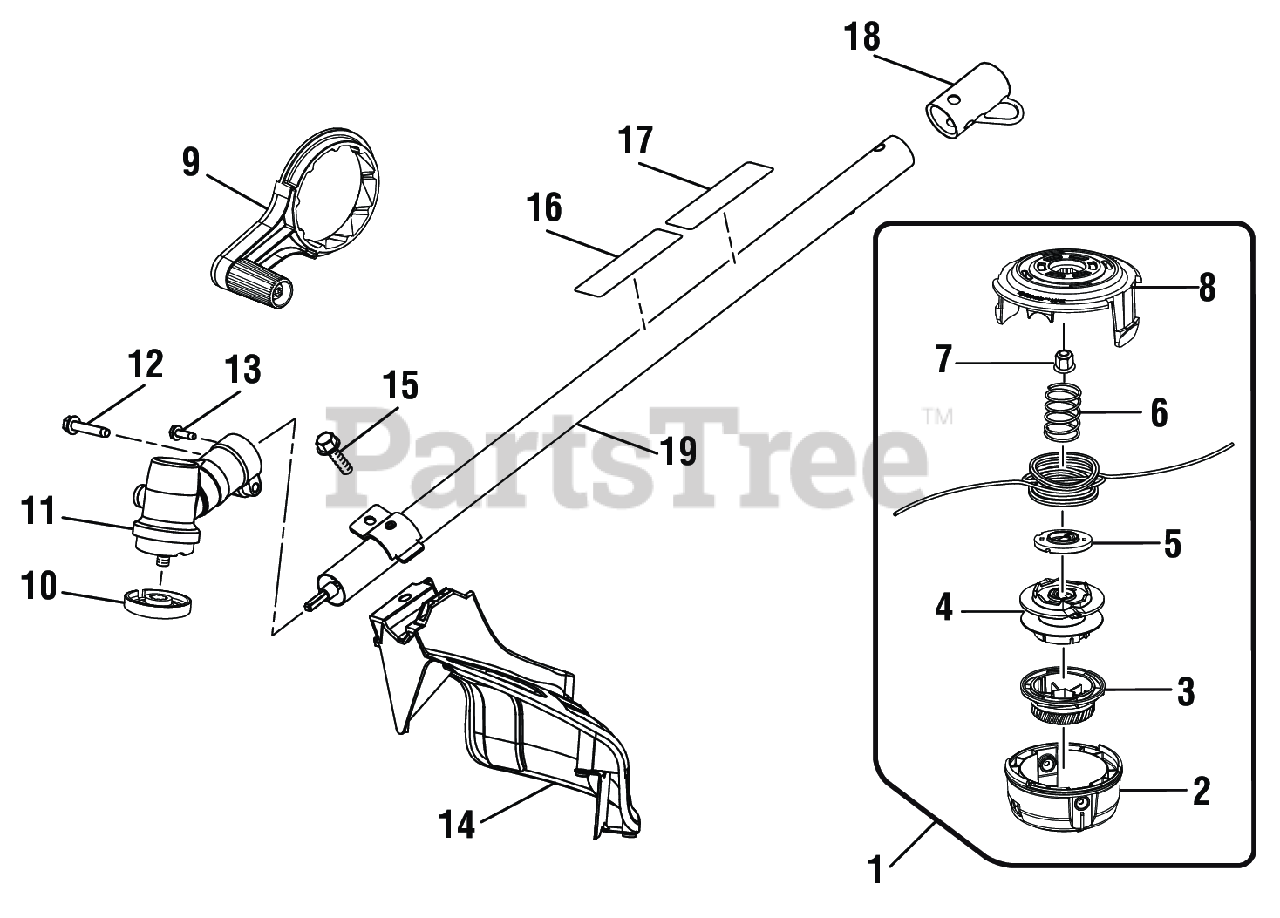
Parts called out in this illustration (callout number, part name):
1	Trimmer Head Assembly (.095)
2	Lower Housing
3	Bump Knob (Green)
4	Spool Assembly
5	String Guide
6	Compression Spring
7	Hex Nut (M8, Left Hand Threads)
8	Upper Housing
9	Crank Handle
10	FLANGED WASHER
11	Gear Case Assembly
12	Screw (1/4-20 x 1-1/4 in., Hex Washer Hd. S.T.)
13	Screw w/Washer (10-24 x 5/8 in., Hex Hd. T.F.)
14	Grass Deflector Assembly (Inc. Key No. 16)
15	SCREW (#1/4-20 X 1-1/4 in. HEX WASHER HD.)
16	Ryobi EXPAND-IT Label
17	Warning Icon Label
18	Storage Hanger Cap
19	Straight Shaft Assembly
